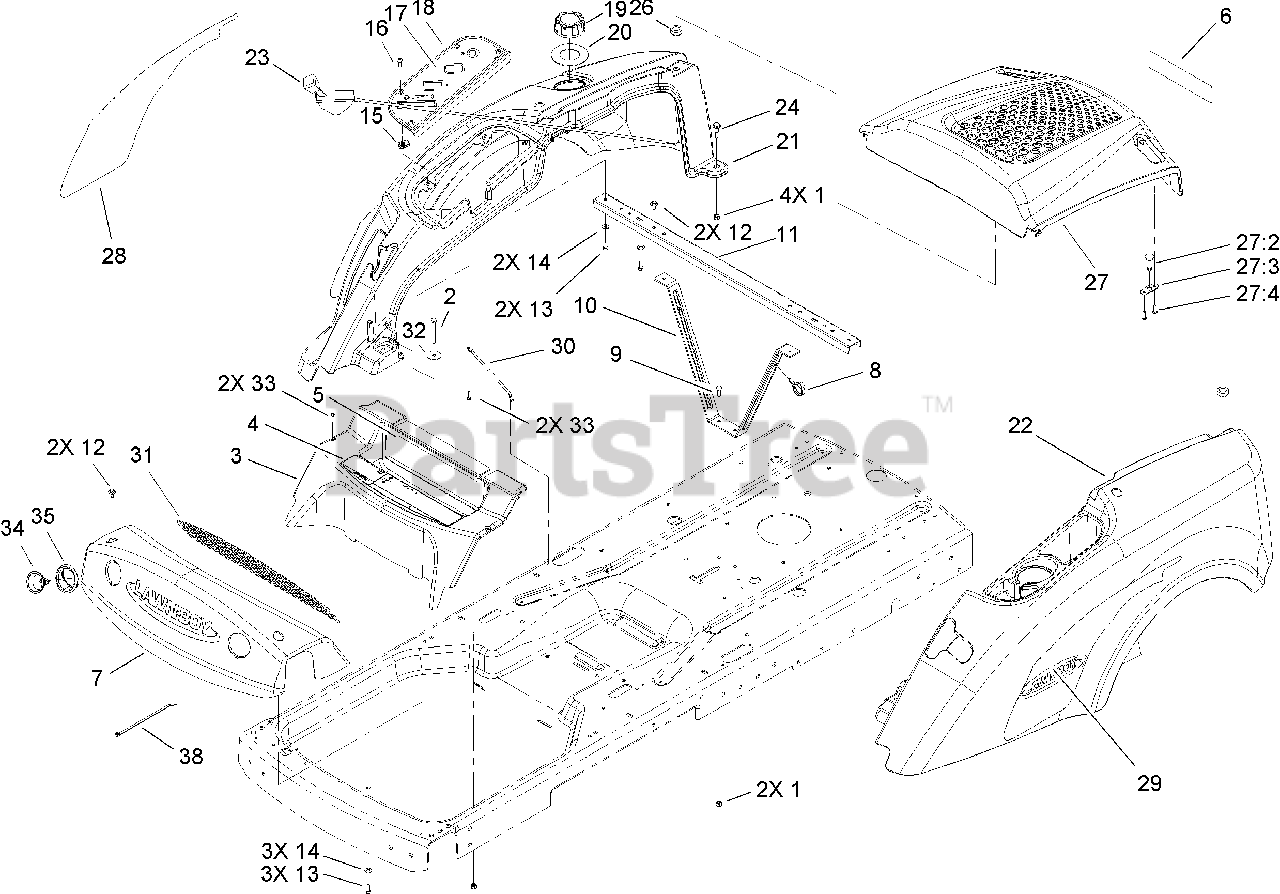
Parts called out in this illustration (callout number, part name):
1	NUT-LOCK, NI
2	SCREW-HH
3	PANEL-KICK
4	DECAL-DANGER
6	DECAL
8	CLAMP-HOSE
9	SCREW-HH
10	BRACE-SUPPORT
11	CHANNEL-CROSS
12	SCREW-HHF
13	SCREW-PLASTITE
14	WASHER-FLAT
16	SCREW-PRH
18	PANEL-CONTROL
19	GAS CAP ASM
20	WASHER-SEAL, RUBBER
21	COVER-SIDE, RH
22	COVER-SIDE, LH
23	CABLE-THROTTLE
24	SCREW-SHOULDER
27	HOOD COVER ASM
30	ROD-SUPPORT
31	FOOTMAT-FOOTREST
32	WASHER-FLAT
33	SCREW-PPH
34	LIGHT-HALOGEN
35	BEZEL-RUBBER
38	TIE-CABLE
